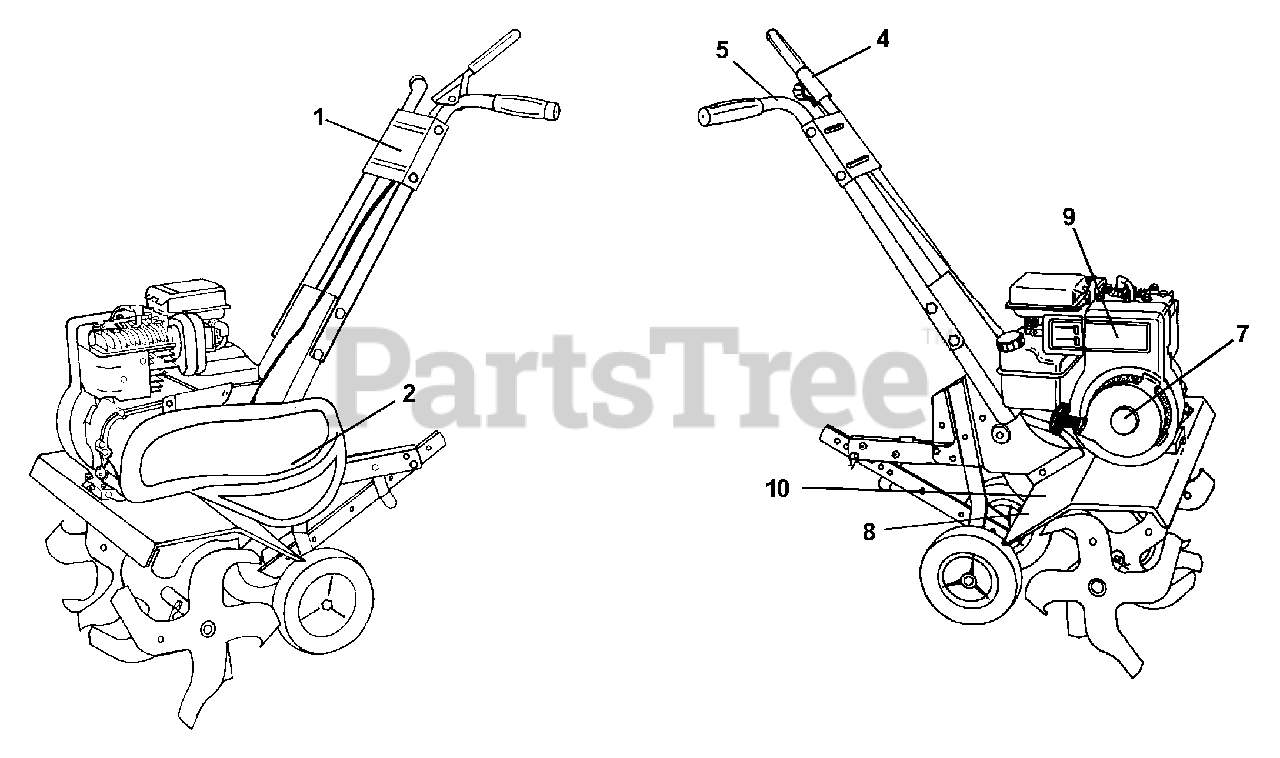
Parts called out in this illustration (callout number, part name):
1	Decal, Logo Control Panel
2	Decal, Logo Belt Guard
4	Decal, Tine Control
5	Decal, Hand Placement
7	Decal, Briggs & Stratton
8	Decal, Warning, Rotating Tines
9	Decal, 5 HP
10	Decal, Warning
